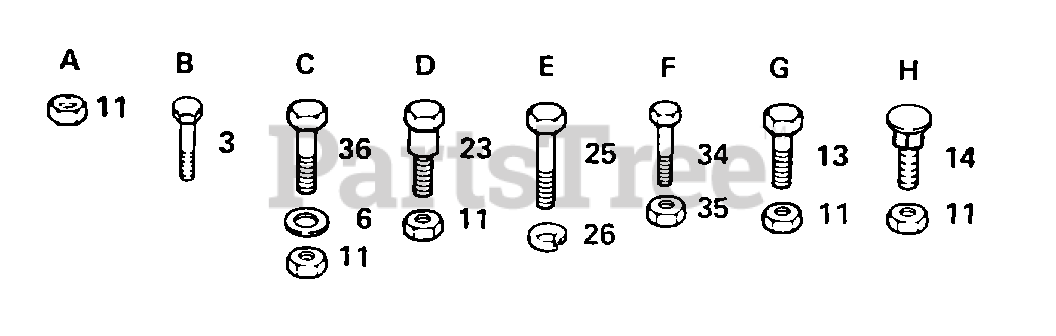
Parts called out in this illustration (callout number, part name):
3	SCREW
6	WASHER
14	BOLT
23	"BOLT, SHOULDER LT"
26	LOCKWASHER
34	BOLT
36	BOLT
